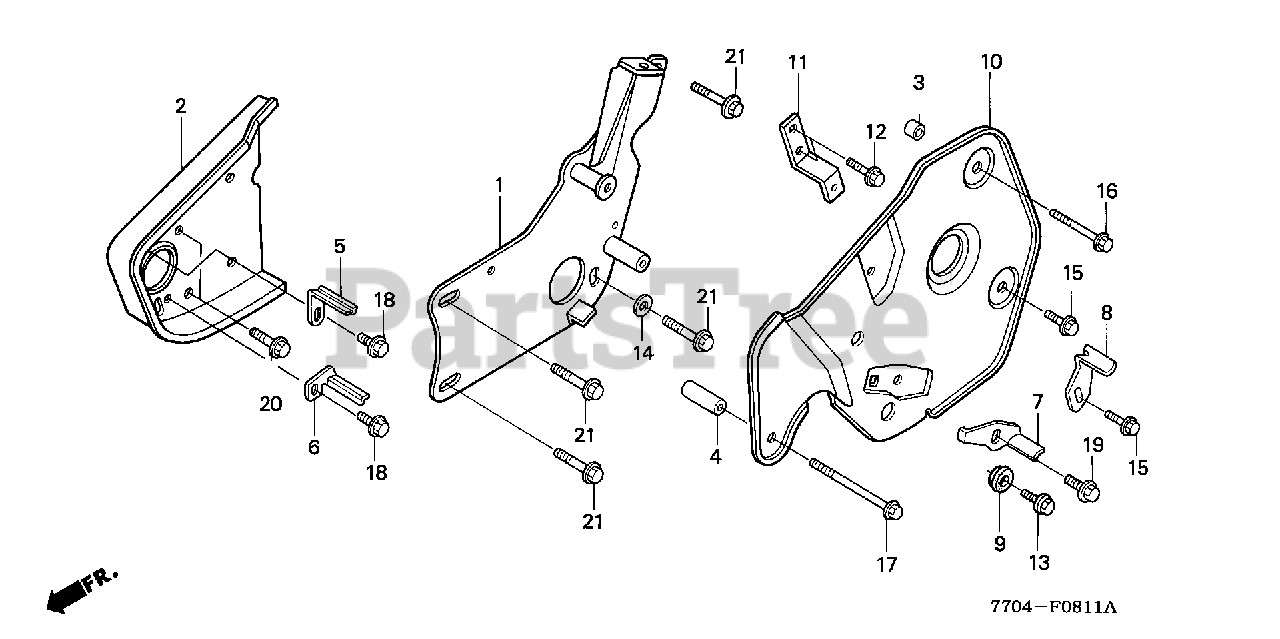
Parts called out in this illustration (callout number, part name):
1	STAY, ENGINE
2	PROTECTOR, BELT (INNER)
3	SPACER, AIR CLEANER ELBOW
4	COLLAR, AIR CLEANER BRACKET
5	STOPPER, BELT (UPPER)
6	STOPPER, BELT (LOWER)
7	STOPPER, BELT (LOWER)
8	STOPPER, RR. BELT
9	GROMMET, WIRE HARNESS
10	STAY, BELT COVER
11	BRACKET, BELT COVER STAY
12	BOLT, FLANGE (6X16) (CT200)
13	BOLT-WASHER (6X16)
14	WASHER, PLAIN (8MM)
15	BOLT, FLANGE (6X12)
16	BOLT, FLANGE (6X28)
17	BOLT, FLANGE (6X45)
18	BOLT, FLANGE (8X10)
19	BOLT, FLANGE (8X12)
20	BOLT, FLANGE (8X16)
21	BOLT, FLANGE (8X20)
